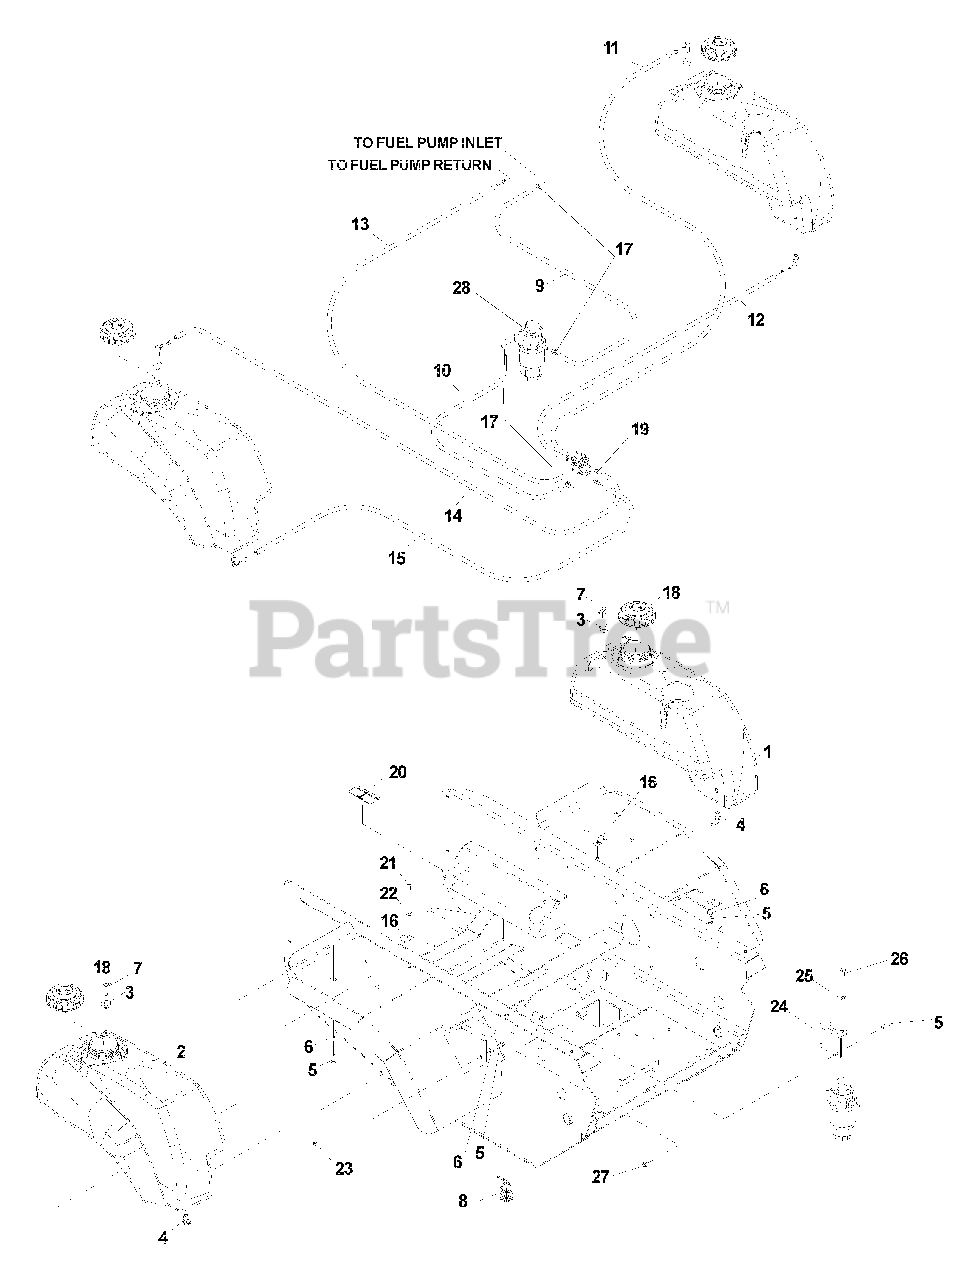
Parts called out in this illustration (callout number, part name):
1	Fuel tank, left
2	Fuel tank, right
3	Grommet, rubber
4	Hose barb, 90°
5	Bolt, 5/16-18 x 3/4
6	Washer, 5/16, sealing
8	Valve, fuel
9	Fuel line (38")
10	Fuel line (35")
11	Fuel line (79")
12	Fuel line (57")
13	Fuel line (54")
14	Fuel line (34")
15	Fuel line (13")
18	Cap, diesel fuel
19	Hose clamp
20	Decal, fuel valve
21	Bolt, 1/4-20 x 3/4
22	Washer, 1/4
23	Nut, 1/4-20, nyloc
24	Mounting bracket
25	Lockwasher, 5/16
26	Bolt, M8-1.25 x 20
27	Nut, 5/16-18, nyloc
28	Fuel filter/pump assembly
28	Fuel filter element w/O-ring
